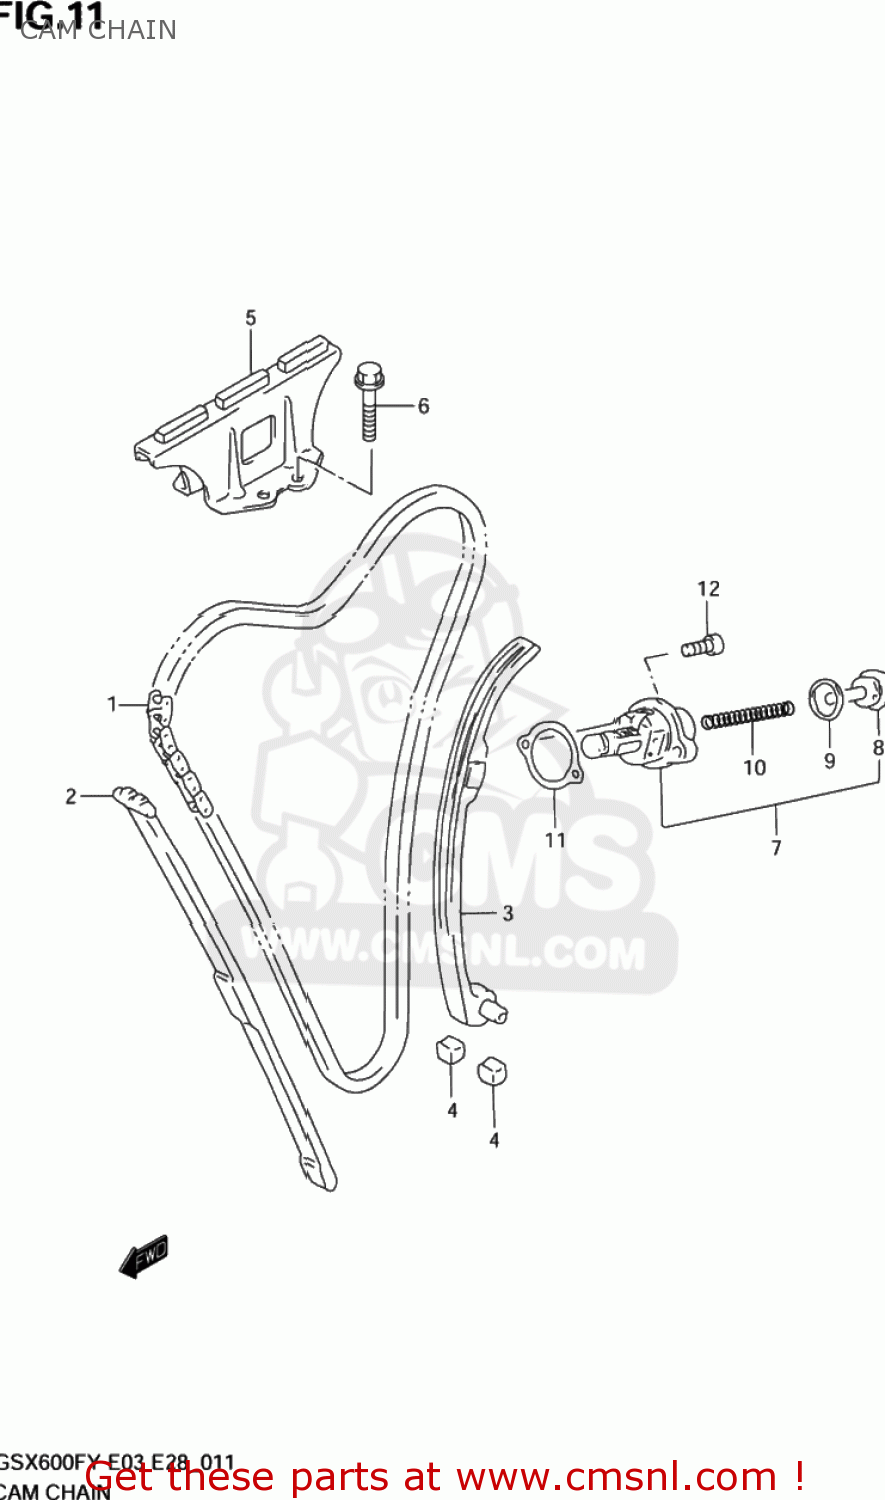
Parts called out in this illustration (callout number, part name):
1	CHAIN,CAMSHAFT DRIVE
2	GUIDE,CAM CHAIN NO.1
3	TENSIONER,CAM CHAIN
4	CUSHION,CAM CHAIN TENSIONER
5	GUIDE,CAM CHAIN NO.2
6	BOLT
7	ADJUSTER ASSY,TENSIONER
8	PLUG
9	GASKET (NAS)
10	SPRING
11	GASKET,TENSIONER ADJUSTER (NAS)
12	BOLT,CL.COVER
